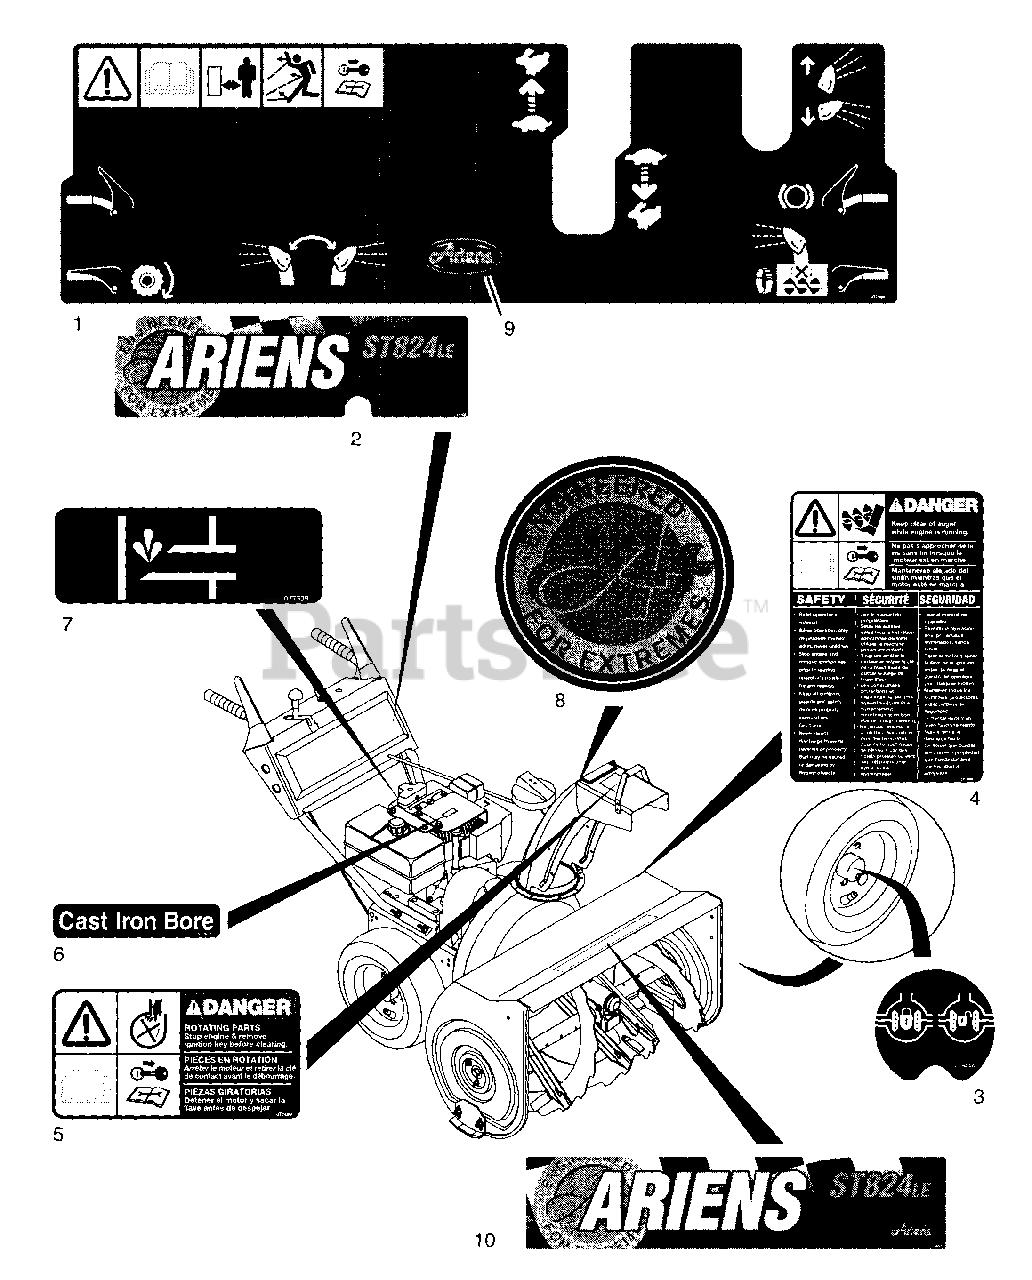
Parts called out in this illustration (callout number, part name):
1	DECAL, DASH
2	DECAL ST824LE
3	DIFFERENTIAL LOCK DECAL
4	DECAL, DANGER
5	DECAL, DANGER - ROT. PARTS
6	DECAL - CAST IRON BORE
7	DECAL, PRIMER "TECUMSEH'S"
8	DECAL, A+
9	DECAL, "ARIENS" JEWEL
10	DECAL, BLOWER HSG ST824LE
